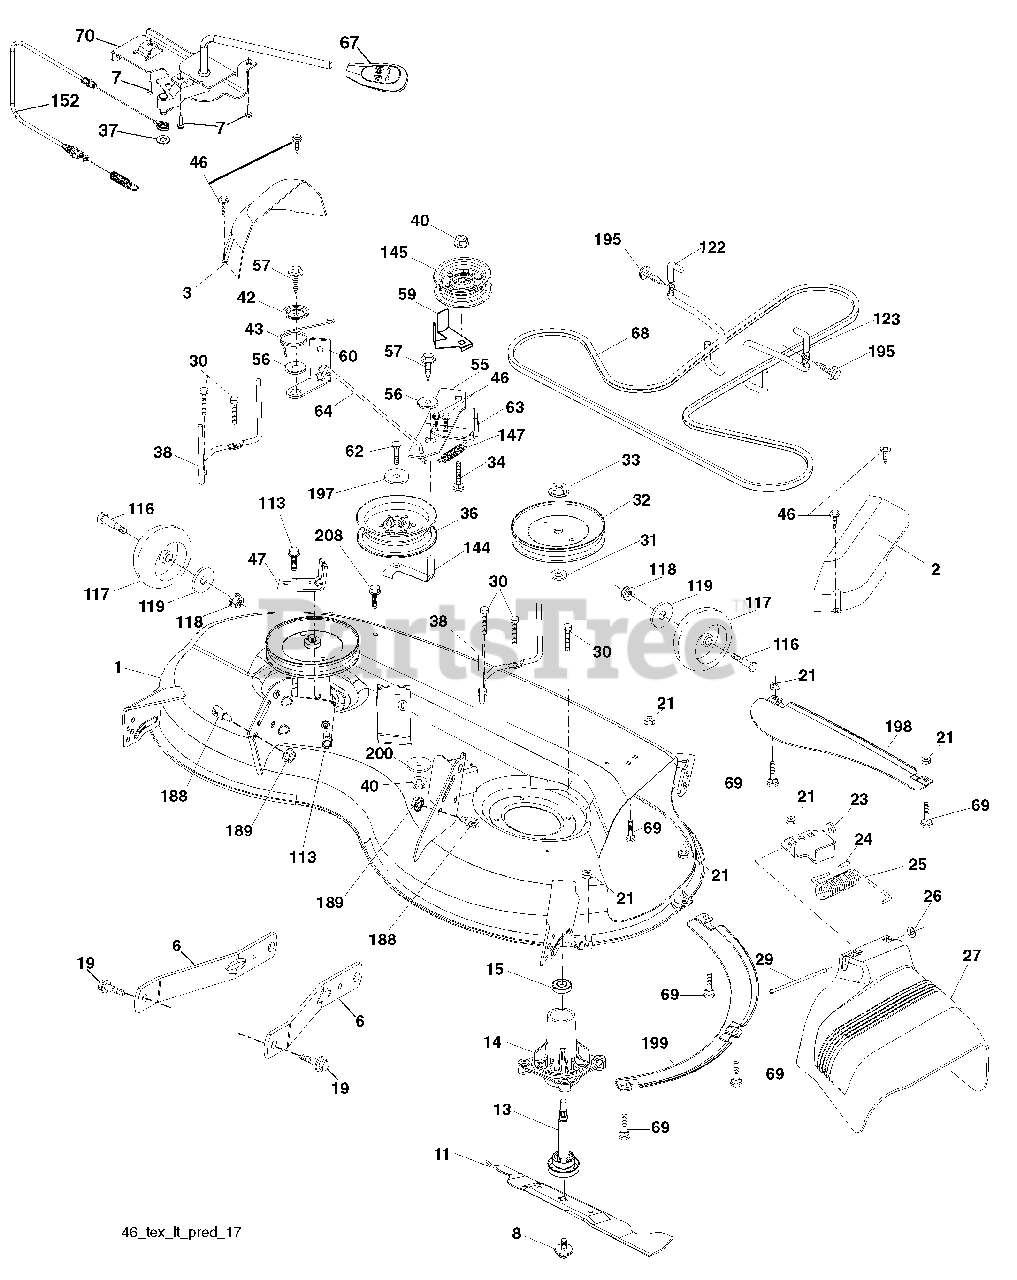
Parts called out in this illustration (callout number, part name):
2	Cover Mandrel RH
3	Cover Mandrel LH
6	Arm Suspension
7	Screw #10 x 0.750 BOS Thread
8	Bolt/Washer Asm. 7/16-20 unf
11	Blade Mower
13	Shaft Assembly, Mandrel
14	Housing, Mandrel
15	Bearing, Ball, Mandrel
19	Bolt, Shoulder
21	Nut
23	Bracket, Deflector
24	Cap, Sleeve
25	Spring, Torsion, Deflector
26	Nut, Push
27	Shield, Deflector
29	Rod, Hinge
30	Screw Thdrol. Rolling Wsh. Hd.
31	Washer, Spacer
32	Pulley, Mandrel
33	Nut, Toplock, Flanged
34	Bolt Carr. Sh. 3/8-16 x 1-1/2 Gr. 5
36	Pulley, Idler, Flat
37	Washer 13/32 x 13/16 x 16 Ga.
38	Keeper Belt LH Mandrel
40	Nut, Lock Flg. 3/8-16 unc
42	Spring Trosion Brake
43	Spring Torsion Retainer
46	Screw
47	Bracket Clutch Cable
55	Arm, Idler
56	Spacer, Retainer
57	Screw Hexwsh. Thd. 3/8-16 x 1
59	Guard, Tuv Idler
60	Arm Brake Mower LH
62	Bolt 3/8-16 unc x 2-1/4 Gr. 5
63	Arm Brake Mower
64	Linkage Brake
67	Handle, Clutch Cable
68	V-Belt
69	Bolt
70	Clutch Asm.
113	Screw 5/16-18
116	Bolt, Shoulder
117	Wheel, Gauge
118	Nut Centerlock 3/8-16 unc
119	Washer 13/32 x 1-1/4 x 12 Ga.
122	Keeper Belt Eng. LH
123	Keeper Belt Eng. RH
144	Keeper Belt
145	Pulley Idler Primary
147	Spring Return
152	Cable Clutch Manual w/Spr.
188	Stud Fastener
189	Nut Lock Hex Flange
195	Screw 3/8-16 x 3/4
197	Washer 13/32 x 13/16 x 12 Ga.
198	Baffle Center Front
199	Baffle Front RH
200	Washer 13/32 x 2 x 10 Ga.
208	Screw Thdrol. 3/8-16 x 1/2
208	Mandrel Assembly
208	Replacement Mower, Complete
